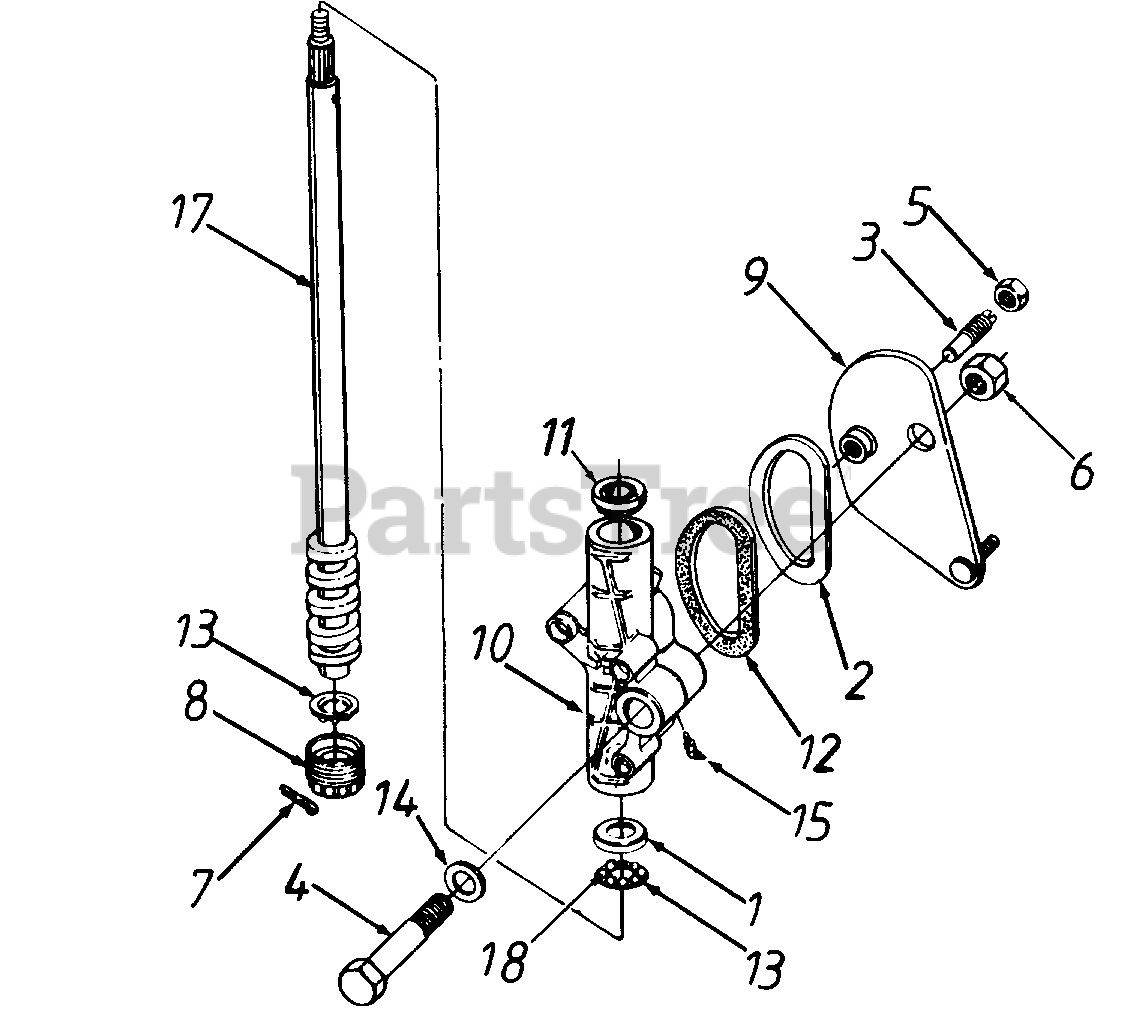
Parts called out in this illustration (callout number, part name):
1	Bearing Cup
2	Seal Retainer
3	Cam Follower
4	Pivot Shaft
5	Hex Jam Nut 9/16-18 Thd.
6	Hex Crown L-Nut 5/8-18 Thd.
7	Cotter Pin 1/8" Dia.
8	Adjustment Plug Ass'y.
9	Steering Arm Ass'y.
10	Steering Hsg. Bushing Ass'y.
11	Oil Seal
12	Seal
13	Ball Retainer
14	Fl-Wash. .781" I.D. x 1.25" O.D.
15	Grease Fitting
17	Steering Shaft Ass'y.
18	Ball Bearing
